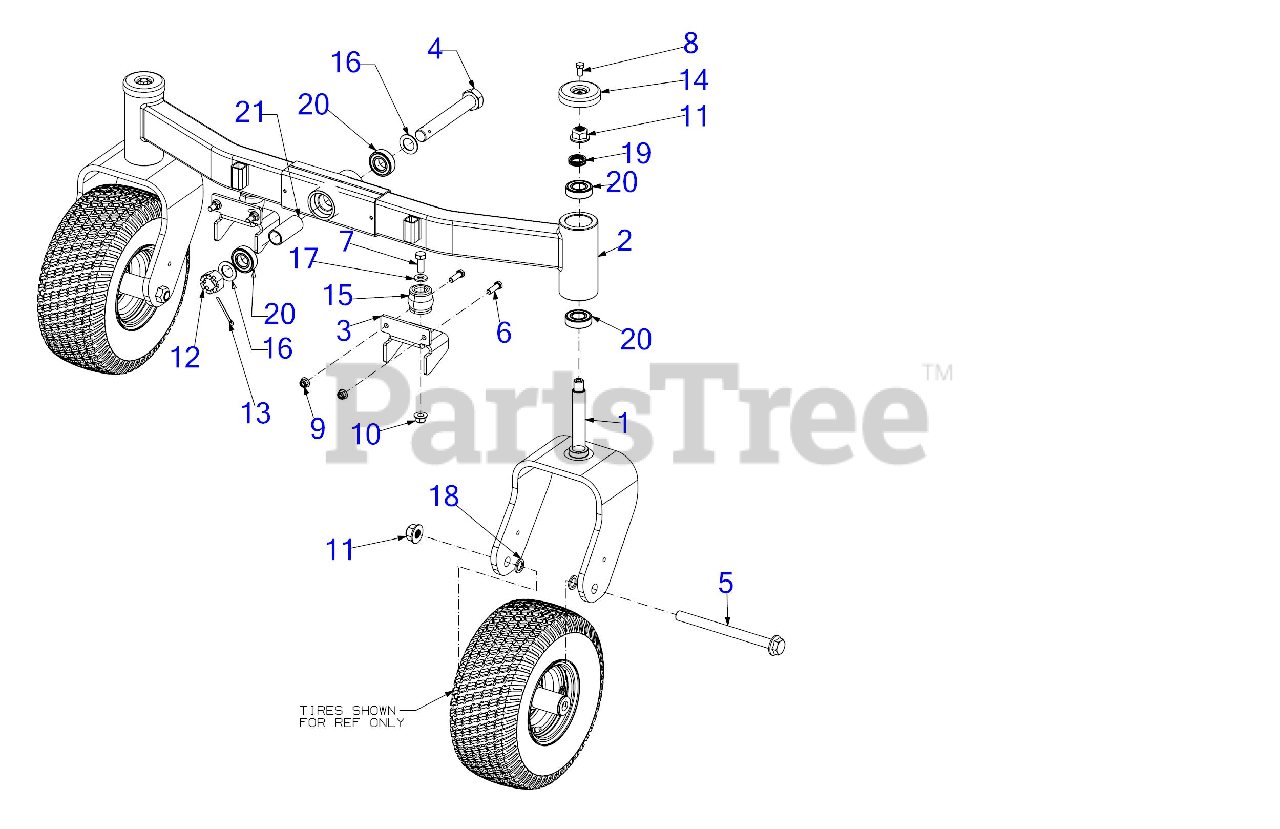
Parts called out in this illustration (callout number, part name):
4	HEX HEAD SCREW 1-14 X 7 GR5
5	SCREW 3/4-16 x 9.00 GR5
6	SCREW 3/8-16 x 1.25 GR5
7	SCREW 1/2-13 x 1.25 GR5
8	SCREW 3/8-16 x .75 GR 5
11	FLANGE LOCK NUT 3/4-16 TOP LOCK
12	CASTLE NUT 1.0-14 GR5
13	COTTER PIN
14	AXLE CAP 3"
15	AXIAL BUMPER
16	FLAT WASHER 1.031 X1.62 X.095
17	FLAT WASHER .510 x 1.000 x .125
18	FLAT WASHER .75 x 1.13 x .10
19	WAVE WASHER
20	BALL BEARING
21	SPACER 1.00 X 1.25 X 2.99
